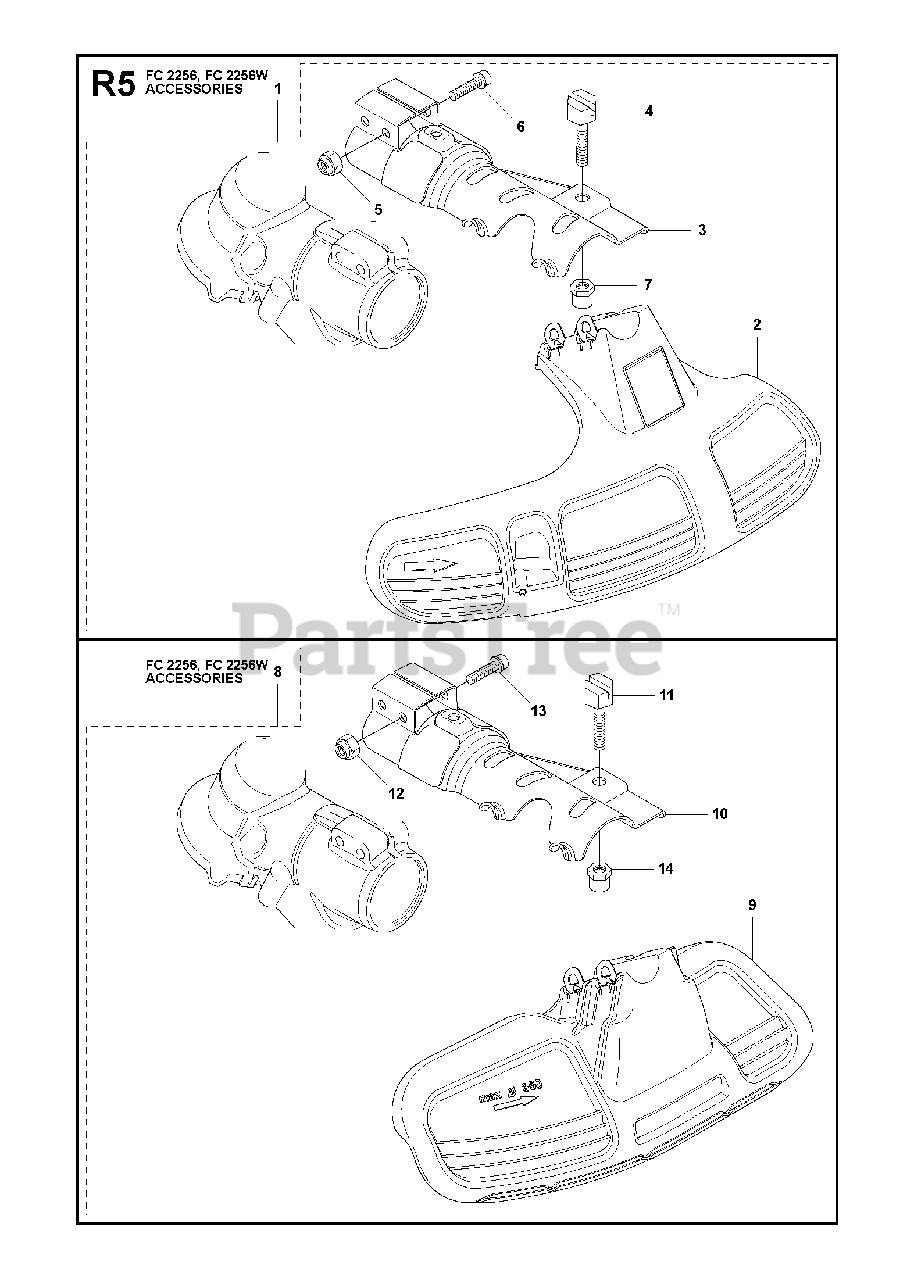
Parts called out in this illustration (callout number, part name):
1	PROTECTION
3	ATTACHMENT PLATE
4	SCREW
5	LOCKNUT M6
6	SCREW
7	SPACING SLEEVE
10	ATTACHMENT PLATE
11	SCREW
12	LOCKNUT M6
13	SCREW
14	SPACING SLEEVE
